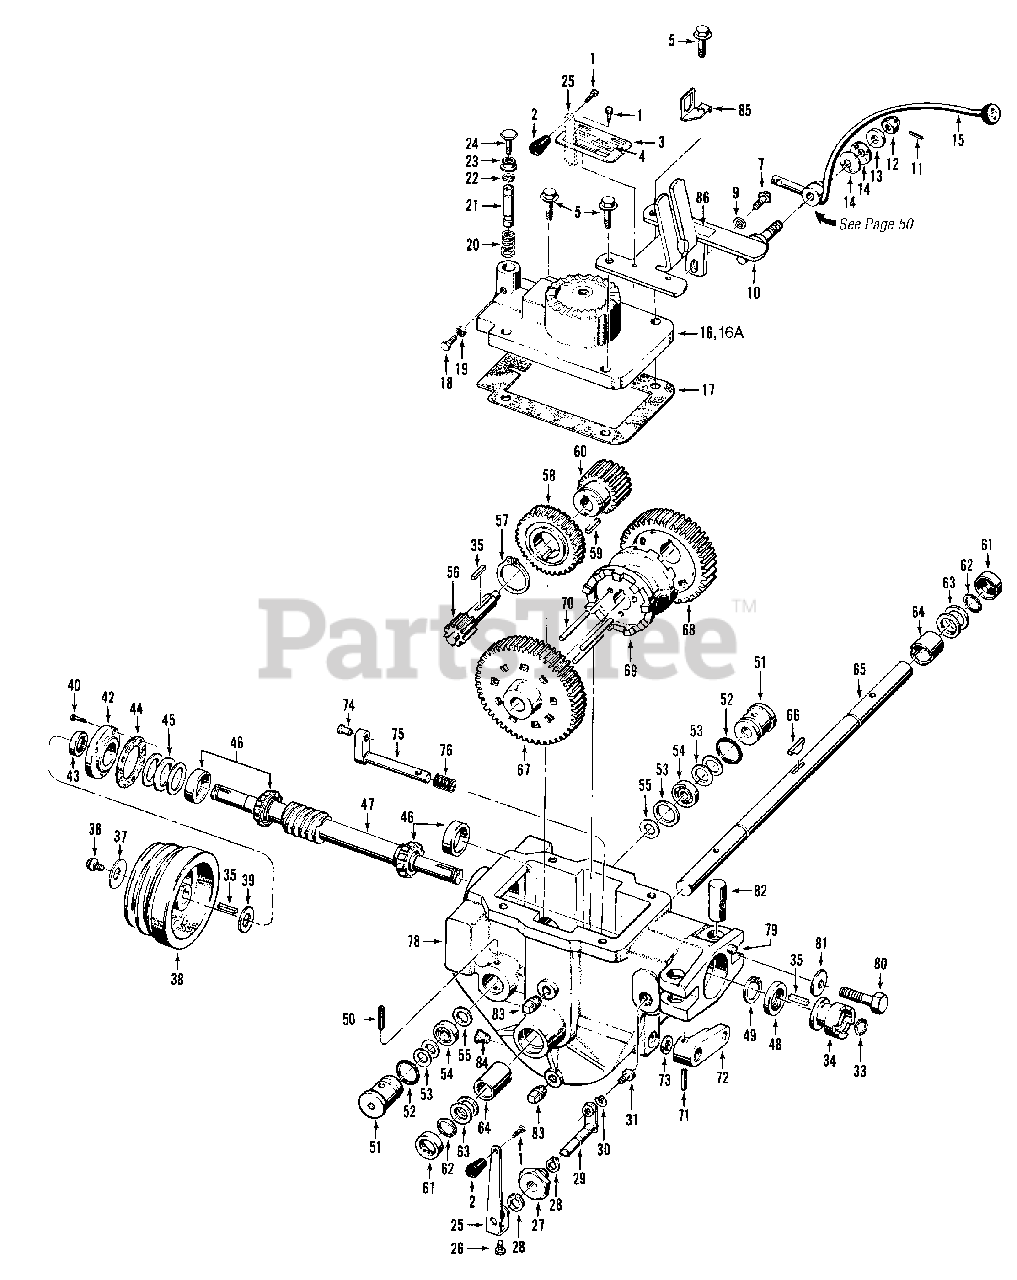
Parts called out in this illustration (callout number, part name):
1	Bolt-hex hd., #10-32 x 3/8", self-locking flange
2	Knob-tines/PTO clutch lever, tapered, plastic
3	Detent Plate-tines/PTO clutch lever
4	Decal-operating instructions, detent plate
5	Bolt-flanged hex hd., 3/8-16 x 1-1/2"
7	Bolt-flanged hex hd., 5/16-18 x 3/4", Grade 5
9	Washer-flat, 5/16", S.A.E.
10	Bracket-shift levers
11	Pin-spring, 1/8"
12	Nut-castle (slotted), 1/2"-20, call Tech Service for tightening instructions
13	Washer-shoulder, 1/2"
14	Washer-disc spring
15	Lever-wheel speed shift
16	Cover-power unit transmission
17	Gasket-transmission cover
18	Bolt-hex hd., 5/16-18 x 1", Grade 5, (remove with care)
19	Nut-hex, 5/16"-18
20	Spring-neutral plunger (remove with care)
21	Plunger-neutral (remove with care)
22	Clip Ring-retains neutral plunger
23	Nut-hex, flange locknut, 3/8"-16
24	Bolt-hex hd., 3/8-16x1-1/2", threaded full length
25	Lever-eccentric, tines/PTO clutch
26	Bolt-hex hd., 1/4-20 x 1/2"
27	Bushing-tines/PTO clutch lever eccentric shaft
28	Retaining Ring-(snap ring), external
29	Eccentric-shaft, tines/PTO clutch lever
30	Lockwasher-hi-collar, 1/4"
31	Screw-socket hd., 1/4-20 x 3/8"
33	Retaining Ring-external
34	Dog Clutch-power unit
35	Key-3/16 sq. x 1"
36	Bolt-hex hd., 5/16-24 x 3/4", self-locking flange, Grade 5
37	Washer-disc spring (concave)
38	Pulley-transmission drive, cast iron
39	Washer-flat, hardened shoulder 1-1/4"
40	Bolt-hex hd., 1/4-20 x 3/4", front bearing cap
42	Cap-front bearing
43	Seal-oil, front bearing cap
44	Gasket-front bearing cap
45	Shim-front bearing cap, 010" thick
45	Shim-as above, .030"
45	Shim-as above, .005"
45	Shim-as above, .062"
46	Bearing & Race
47	Shaft-main drive, power unit
48	Seal-oil, drive shaft, rear
49	Retaining Ring-(snap ring), internal
50	Pin-roll (spirol), 1/4 x 2"
51	Plug-retaining, pinion bearing
52	O-Ring-retaining plug
53	Shim-retaining plug, 1-1/64" inner dia., .033" thick
53	Shim-same as GW-1132-1, .062"
53	Shim-same as GW-1132-1, .010"
54	Bearing-ball, pinion shaft
55	Washer-pinion shaft
56	Stem Pinion-slow speed gear & shaft
57	Ring-retaining, external
58	Worm Gear-bronze, wheel drive
59	Key-3/16" x 5/8"
60	Gear-fast speed pinion
61	Seal-oil, wheel shaft
62	Retaining ring-external
63	Shim-wheel shaft, 1-1/64" inner dia., .062" thick
63	Shim-as above, .030" thick
63	Shim-as above, .015" thick
63	Shim-as above, .010" thick
63	Shim-same as above, .005" thick
64	Bushing-bronze, wheel shaft bearing
65	Shaft-wheel, 15-5/8"
66	Key-Hi Pro, 1/4" x 1-3/4"
67	Gear-slow speed, wheel drive
68	Gear-fast speed, wheel drive
69	Dog Clutch-wheel drive
70	Pin-clutch guide, 1/4" diameter
71	Pin-roll, 3/16" x 1-1/4" (spirol)
72	Lever-eccentric, wheel speed shifting
73	Seal-oil, eccentric shaft
74	Pin-eccentric shaft, wheel speed shifting
75	Eccentric Shaft-wheel speed shifting
76	Spring-eccentric shaft
78	Housing-power unit transmission (Empty housing without covers, shafts, gears, seals, etc.)
79	Pin-alignment
80	Bolt-hex hd., 1/2-13 x 2" Grade 5
81	Washer-disc spring (concave), domed side faces bolt head
82	Post-with threaded hole for Ref. No. 80
83	Plug-pipe, 1/4"
84	Plug-red plastic, thread protector.
85	Clip-forward interlock system plug connector (see page 47)
86	Decal-forward interlock wire harness
